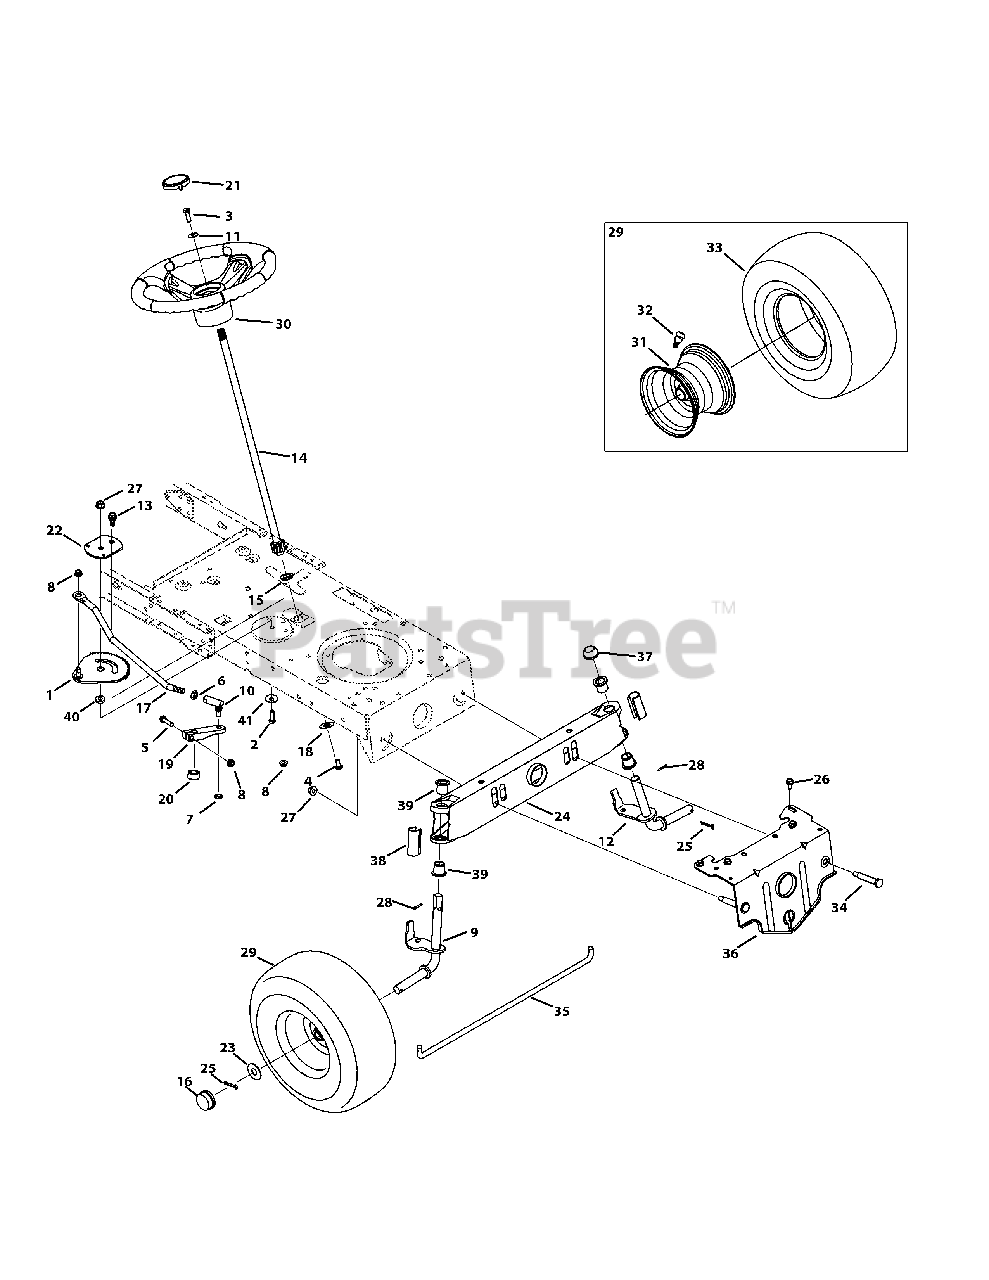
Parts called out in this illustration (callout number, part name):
1	Front Steering Gear Assembly
2	Hex Screw, 3/8-16 x 1.00
3	Hex Screw, 5/16-18 x 1.00, Lock
4	Machine Screw, 5/16-18 x .750
5	Hex Screw, 5/16-18 x 1.75
6	Jam Nut, 7/16-20
7	Jamlock Nut, 3/8-24
8	Flangelock Nut, 5/16-18
9	Front RH Axle
10	Ball Joint, 7/16-20
11	Bell Washer, .340 x .872 x .060
13	Shoulder Bolt, 5/16-18 x .435 x .350
14	Steering Shaft, 5/8
15	Flange Bearing, 5/8
17	Steering Link
18	Cap, 1.25 x .16
19	Steering Block
20	Spacer, .71 x .125 x .56
21	Cap, Troy-Bilt
22	Stabilizer Plate
23	Flat Washer, .781 x 1.590
25	Cotter Pin, 5/32 x 1.25
26	Screw, 5/16-18 x .750
27	Flangelock Nut, 3/8-16
28	Cotter Pin, .125 x .75
29	Wheel Assembly
30	Steering Wheel
31	Rim Asm, 6.0 x 4.5
32	Valve, tubeless Air
33	Tire, 15 X 6 X 6 Rd Shldr
34	Shoulder Bolt, 3/8-16 x .500 x 2.38
36	Pivot Bar Bracket
37	Push Cap, 3/4
38	Standard Axle Cap
39	Flange Bearing, .760 x .941 x 1.0
40	Spacer, .38 ID x .854 OD x .20
41	Bell Washer, .390 x 1.13 x .062
